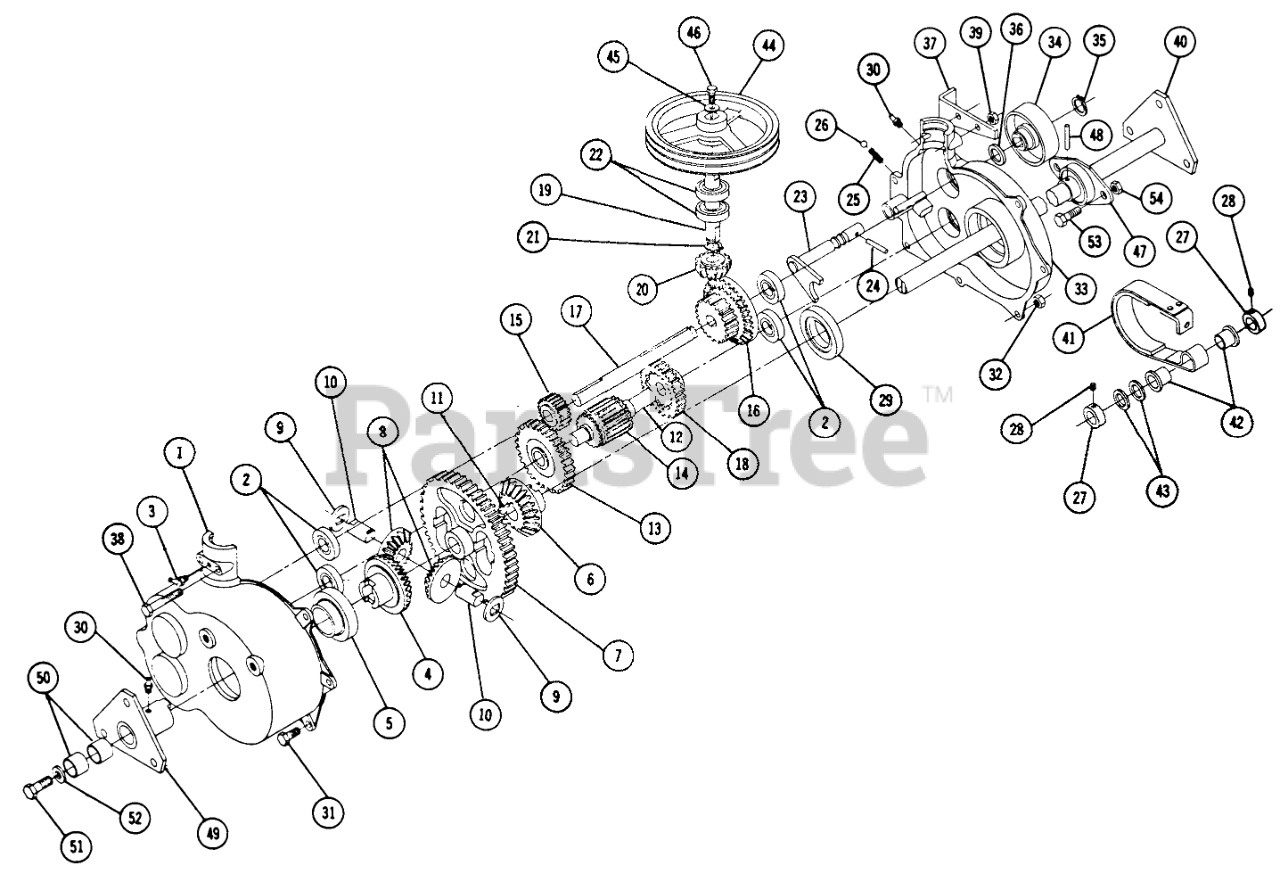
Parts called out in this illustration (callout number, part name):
3	FITTING-GREASE
11	WOODRUFF KEY
21	SNAP RING- 5/8 EXT
24	PIN-SPIROL
26	BALL-DETENT
28	Set Screw Nylok
31	Bolt, 5/16-18 X 7/8
32	Nut 5/16-18 Keps
35	SNAP RING- 5/8 EXT
37	Bracket Shift Rod
38	Bolt Hex 5/6-18 X 2-1/2
39	Nut-Nylok
40	Ass-y. Axle
45	Washer
46	Bolt, 5/16-18 x 5/8
48	Spirol Pin
49	Ass-y Hub Flange
50	BUSHING-BRONZE
51	Bolt 3/8-16 x 3/4 Hex
52	WASHER
53	Bolt Hex 3/8-16 x 5/8
